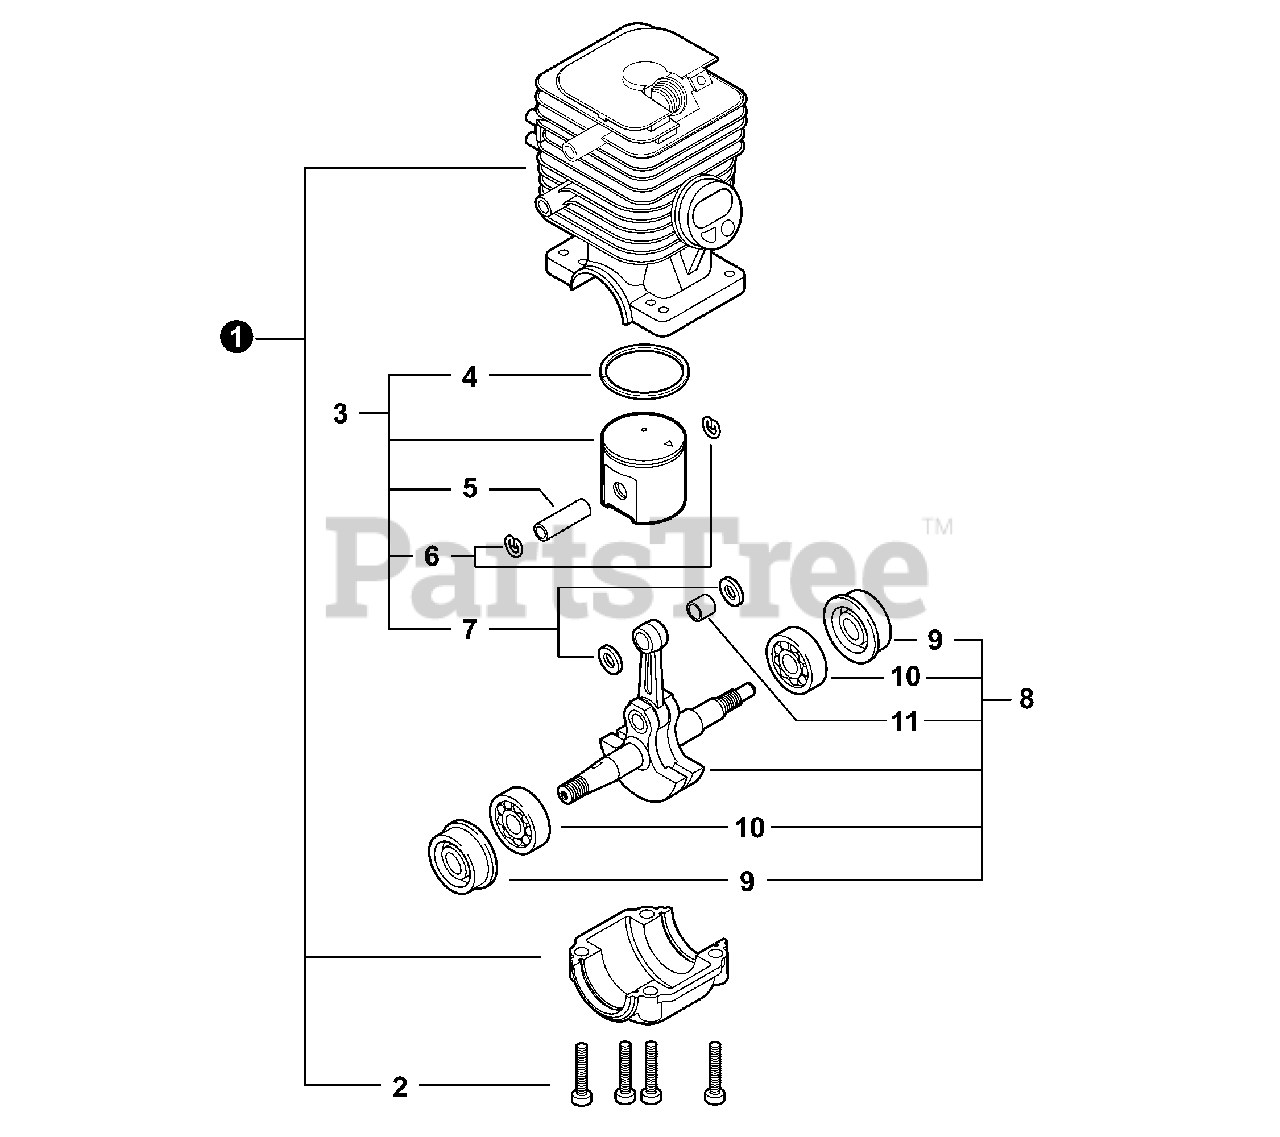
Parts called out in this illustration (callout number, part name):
1	CRANKCASE KIT
2	BOLT, TORX 5×25
3	PISTON KIT
4	RING, PISTON
5	PIN, PISTON
6	RING, SNAP
7	WASHER, THRUST
8	CRANKSHAFT ASSY
9	SEAL, OIL 12
10	BEARING, BALL - 6201 C3
11	BEARING, NEEDLE 8
